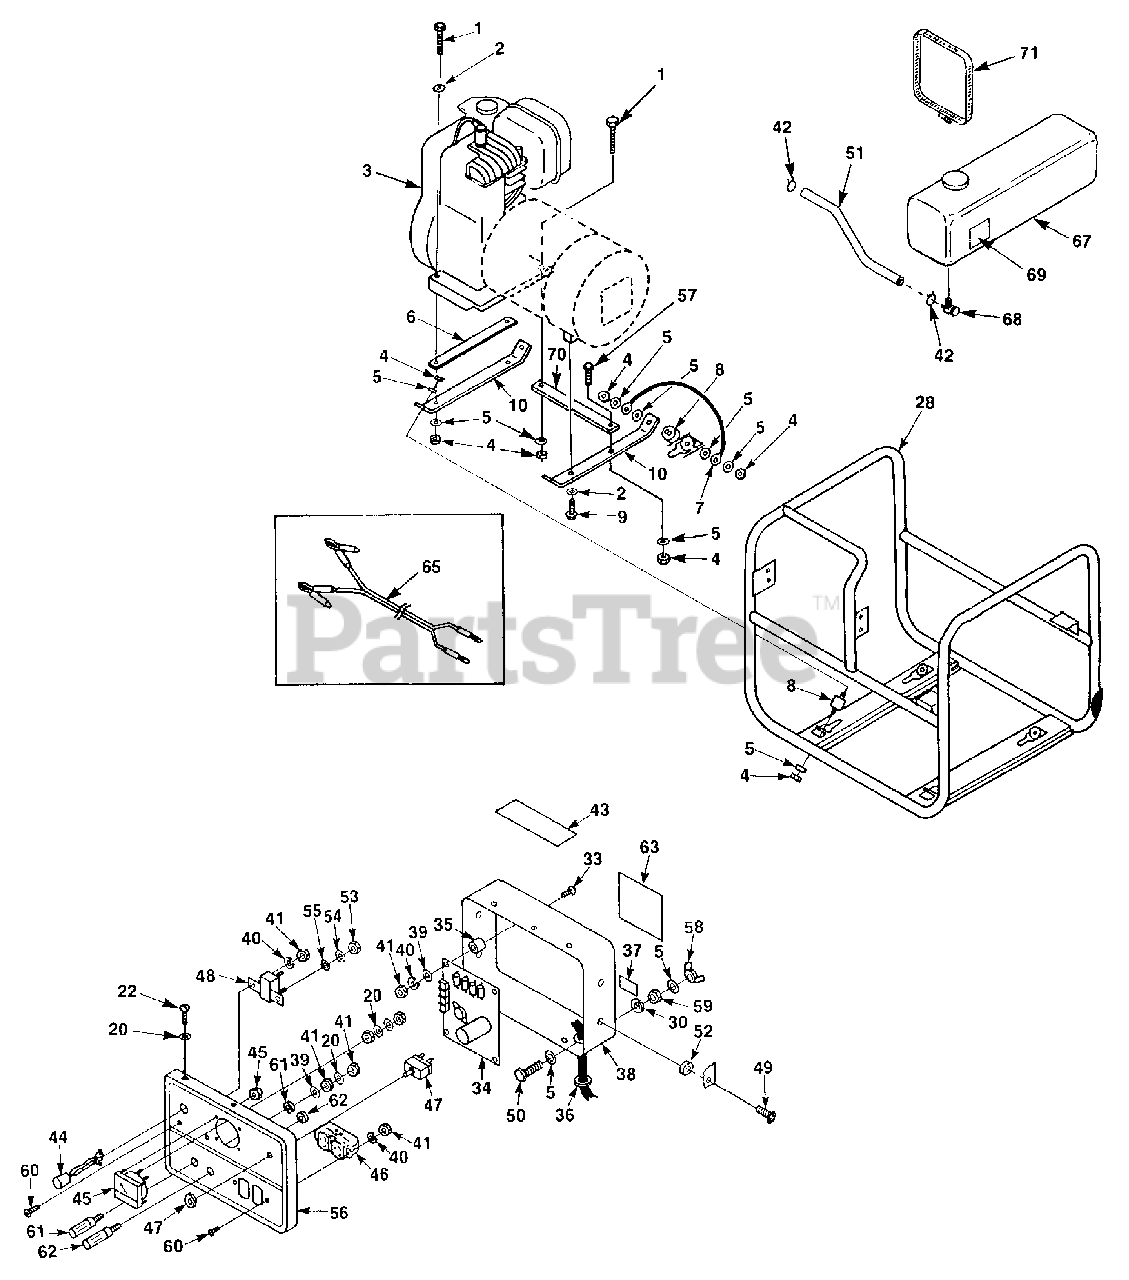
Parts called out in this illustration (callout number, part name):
1	SCREW- Hex Hd. 5/16-18 x 1 3/4"
2	WASHER- Lock Int.
4	NUT- Hex 5/16-18
5	WASHER-lnt. 5/16"
7	STRAP-Ground
8	ISOLATOR-Vibration
9	SCREW-Hex taptite 5/16-18 x 1"
10	SUPPORT-Eng. & Gen.
20	WASHER-Lock Int. #8
22	SCREW-Mach rd. hd. 8-32 x 3/8"
28	ROLL CAGE
30	WASHER- Lock 5/16"
33	SCREW- #8- 32 x 5/8"
34	VOLTAGE REGULATOR
35	SPACER- 1/4"
36	GROMMET
37	DECAL-Ground
38	CONTROL BOX
39	WASHER-Flat #8
40	WASHER-Lock #8
41	NUT- Hex 8-32
42	CLIP- Hose
43	DECAL- Warning
44	PILOT LITE
45	VOLTMETER
46	RECEPTACLE- Duplex
47	BREAKER- Circuit (AC)
48	BREAKER- Circuit (DC)
50	SCREW- Steel
51	FUEL HOSE
52	GROMMET- Isolator
53	NUT- Hex 10-32
54	WASHER- Flat #10
55	WASHER- Lock #10
56	CONTROL PANEL
57	SCREW- Cap hex hd. 5/16-18 x 1"
58	NUT-Wing 5/16-18
59	NUT- Hex 5/16-18
60	SCREW- Pan hd., 8-32 x 3/8"
61	POST- Binding (Black)
62	POST- Binding (Red)
63	DECAL- Caution
65	LEAD- D.C.
67	TANK- Fuel
68	VALVE- Fuel
69	DECAL- Fuel valve
70	DAMPNER- Vibration
71	CLAMP- Tank
